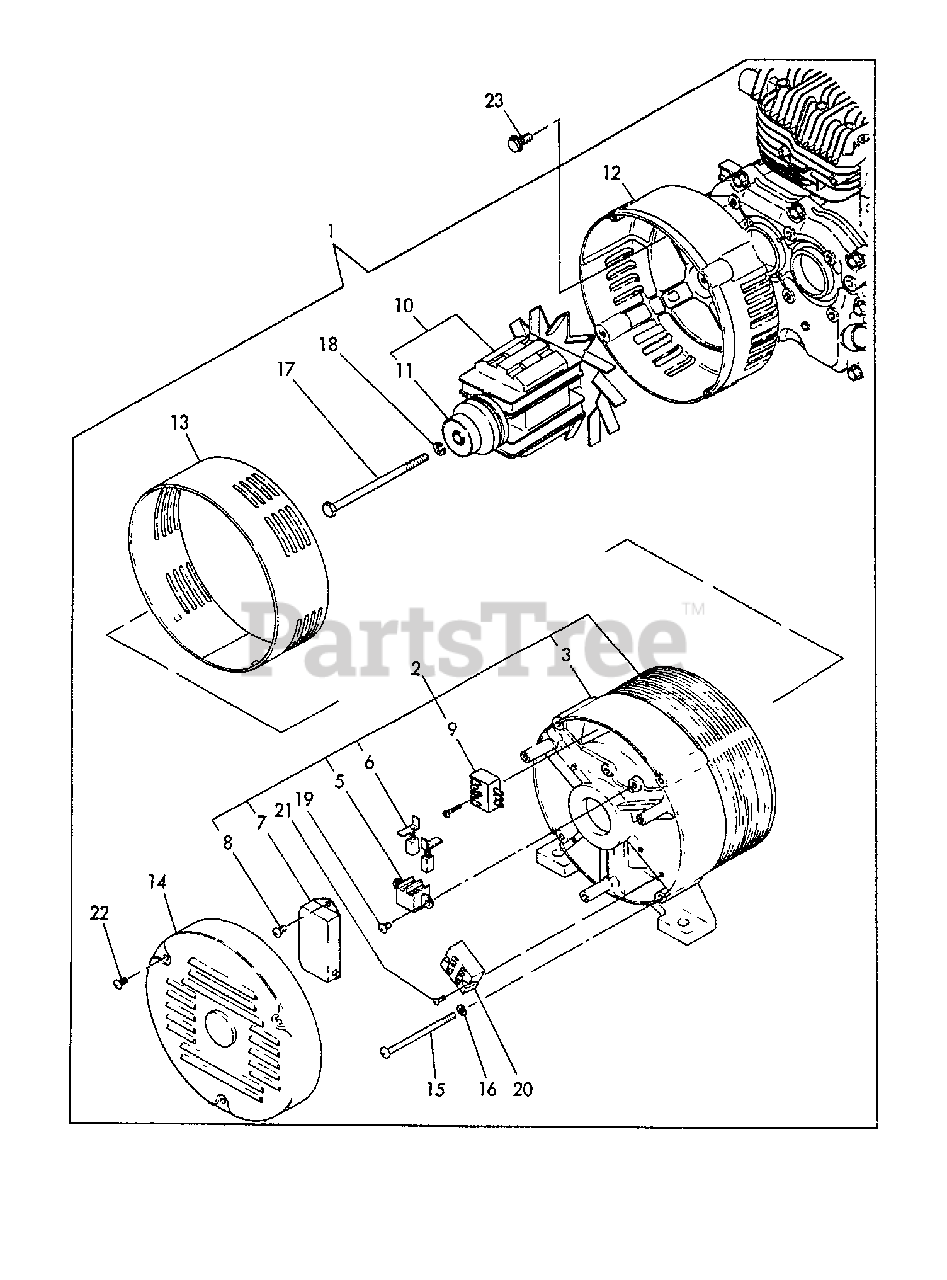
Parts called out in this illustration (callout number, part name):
1	GENERATOR 3.8KVA
2	STATOR ASSY
3	COVER - REAR
5	HOLDER, BRUSH
6	BRUSH
7	A.V.R.
8	SCREW - 4×14
9	RECTIFIER
10	ROTOR ASSY
11	BEARING, BALL
12	COVER, FRONT
13	CLAMP
14	COVER, END
15	BOLT, THROUGH
16	LOCKWASHER - 6
17	BOLT
18	LOCKWASHER - 10
19	SCREW - 5×14
20	TERMINAL
21	SCREW - 5×14
22	SCREW - 4×8
23	BOLT - 8×20 -- PLATED
